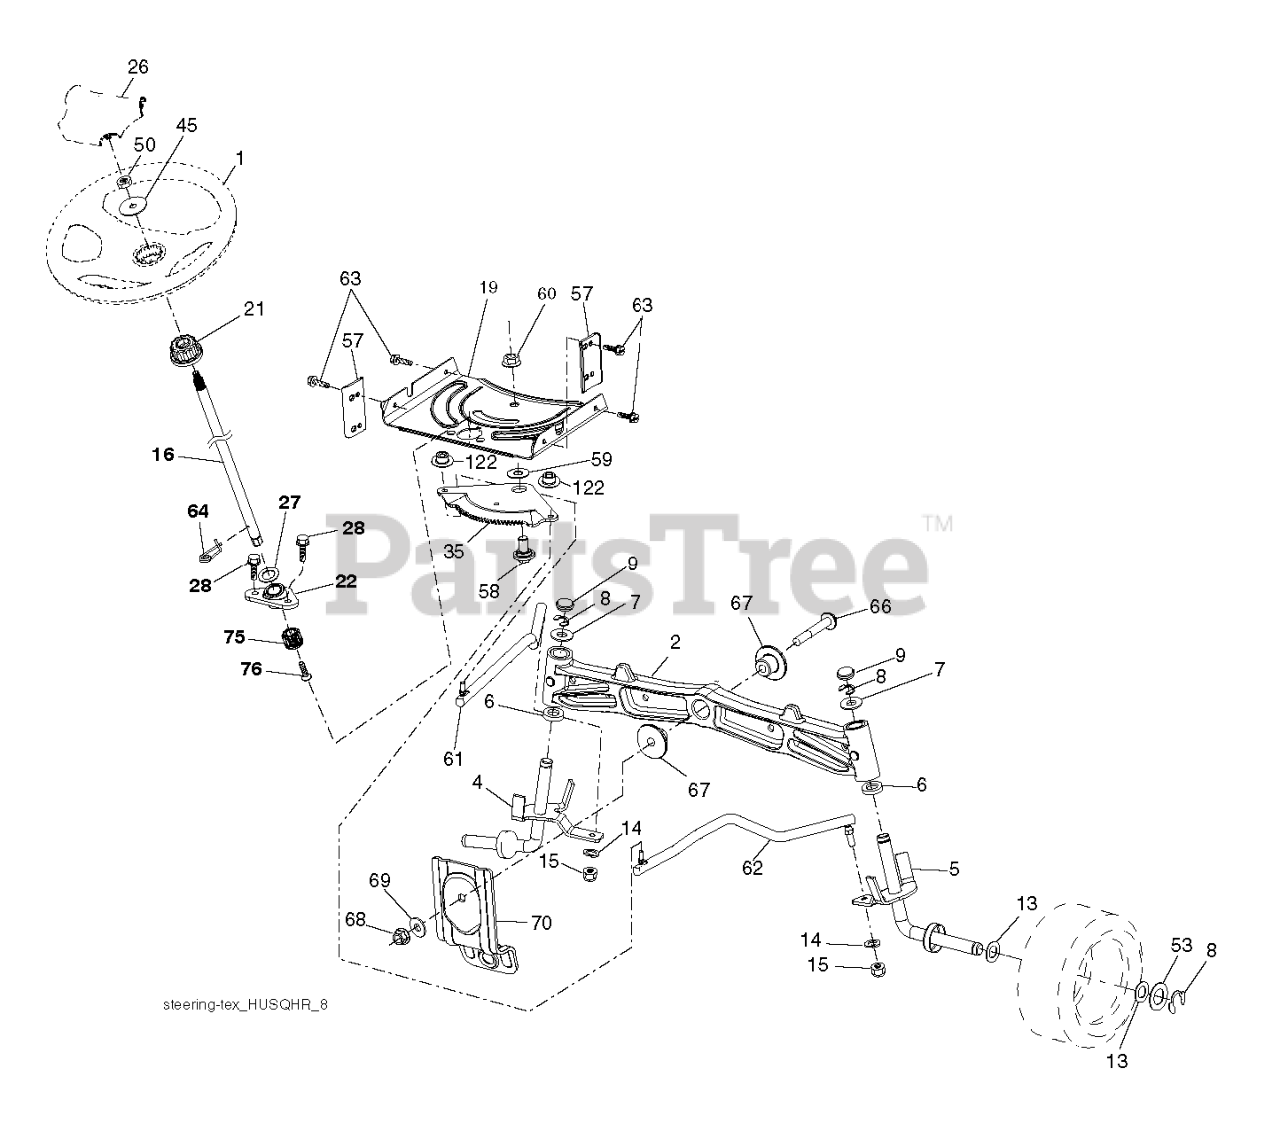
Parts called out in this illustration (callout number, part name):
1	WHEEL.STEER.HUSQ.SR.498.OVMLD
2	AXLE.CAST.IRON
4	SPINDLE.WELDED.LH.15"TEX
5	SPINDLE.WELDED.RH.15"T
6	WASHER THRUST
9	CAP.SPINDLE.BLACK
15	NUT CROWNLOCK 3/8-24
16	SHAFT.STEER.2HIGH.SPLND.PLATED
19	PLATE.STEER.DDL.NLT/NG
21	ADAPTER.WHEEL.STEER.SPLND.ALUM
22	BEARING.SHAFT.STEER.LOWER.625
26	INSERT.CAP.STRG.WH.GRAY
26	INSERT.CAP.WHL.STRG.HUSQ.PREM
28	SCREW, 3/8-16X3/4
35	GEAR.SECTOR.PLATE.DDL.
45	WASHER 9/16"ID, 2 3/8"OD
50	NUT.HEX.1/2-20
50	NUT LOCK FLG 3/8-16 UNC
53	WASHER.HARDENED
57	BRACKET.UPSTOP.TEX
58	BOLT.SHOULDER.SECTOR.P
59	WASHER.THURST.SECTOR.S
60	NUT FLANGE LOCK 5/8-11
61	DRAGLINK.LH.BALLSTUD.D
61	Links
62	Links
62	DRAGLINK.RH.BALLSTUD.D
63	SCREW
64	RETAINER.CLIP.SPRING.S
66	BOLT HEX FGHD 7/16-14 X 3 SERR
67	BUSHING.PM.FRONT AXLE
68	NUT.LOCK.FLANGE.7/16
69	WASHER.1.5X.505X.118
70	BRACKET.FRT.DECK.SUSP.RR.MT431
75	PINION.ZINC PLATED
76	SCREW HEAD SOCKET LRVB
122	CAP.GEAR.SECTOR.TEX
